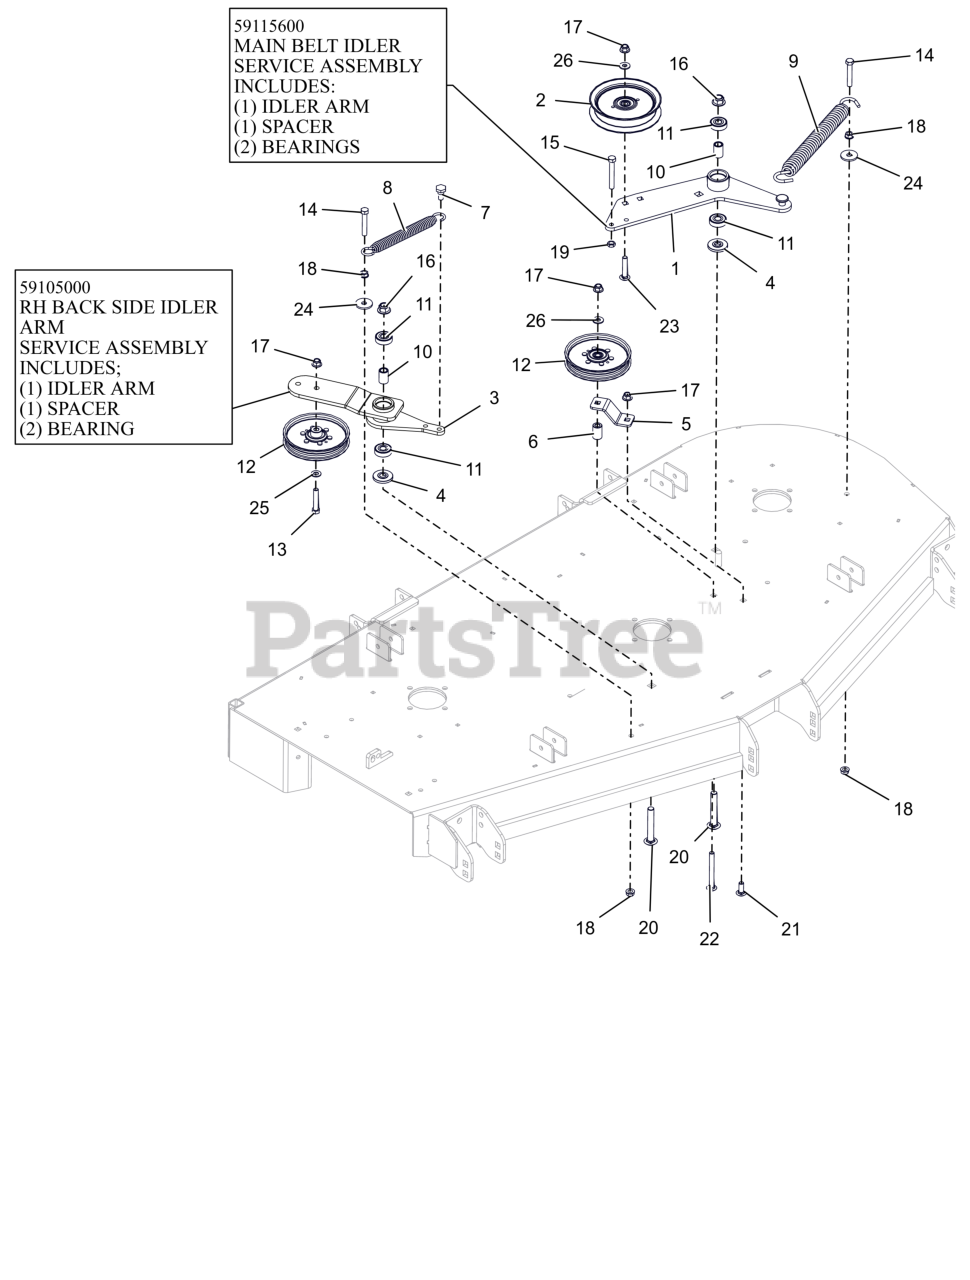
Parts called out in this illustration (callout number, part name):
1	WLDMT, DECK PTO IDLR ARM
1	ASSEMBLY, MAIN BELT IDLER
2	IDLER, FLAT 5.00"
3	WLDMT, DECK RH IDLER ARM
3	RH BACKSIDE IDLER ARM ASSEMBLY
4	SPACER, IDLER ARM
5	PTO FIXED IDLER MTG BRKT -RED
6	BUSHING, SLV .380X.750X1.190
7	BLT,SHLDR EP .38-16X.30 HEX YZ
8	SPRING, EXTENSION
9	SPRING, EXTENSION
10	SPACER .510 X .75 X 1.1485
11	BRG-BALL .500X1.38X.437
12	PULLEY, FLAT IDLER
13	BLT,HEX .38-16X2.00 G5 ZCC
14	BLT,HEX .38-16X2.25 G5 ZCC
15	BLT, HEX .38-16X2.75 G5 ZCC
16	NUT,NYL-FLG .50-13 GF ZCC
17	NUT,NYL-FLG .38-16 GF ZCC
18	NUT, SPNLK-FLG .38-16 G5 ZCC
19	NUT-JAM .375-16 G2 ZCC
20	BTL,RHSSN .500-13 X 3.25 G5 ZCC
21	BLT,RHSSN .38-16X1.00 G5 ZCC
22	BLT,RHSSN .38-16X3.50 G5 ZCC
23	BLT,RHSSN.375-16X2.00 G5 ZCC
24	WSHR,FLT .406X1.375X.135 ZCC
25	WSHR,FLT .406X.812X.065 ZCC
26	WSHR,FLT .375X.875X.083 ZCC
